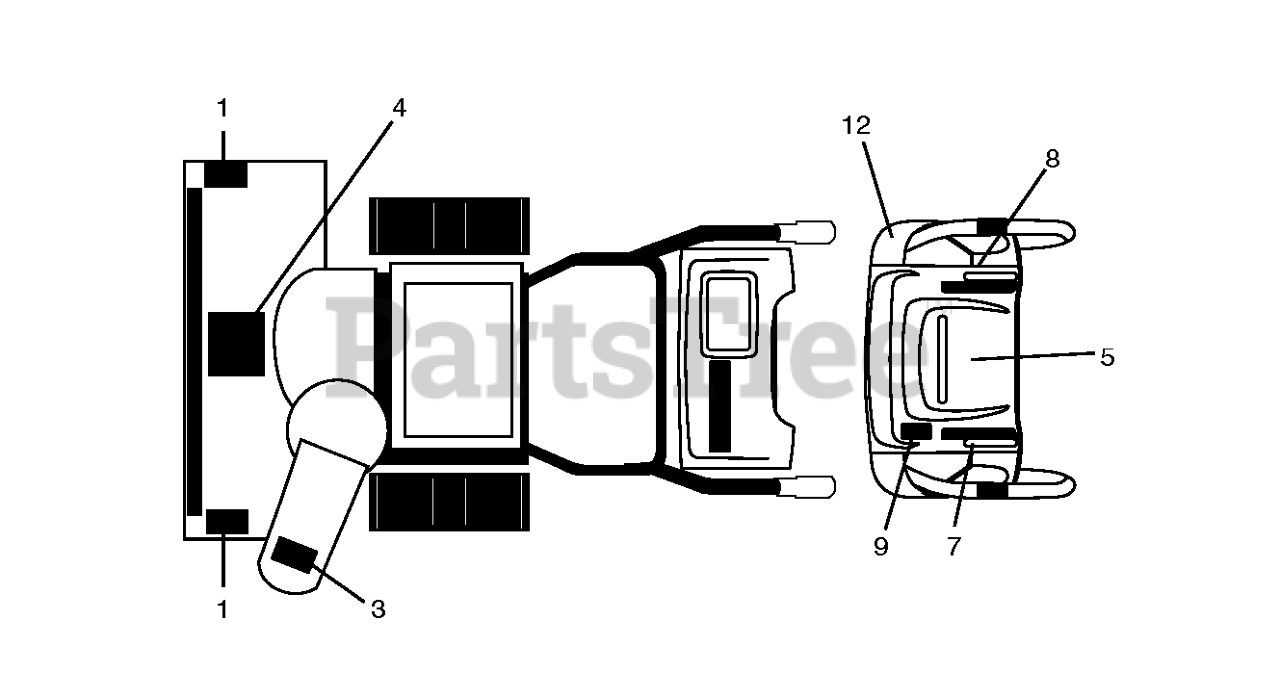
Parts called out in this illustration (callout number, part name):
1	DECAL.SNOWTHR.AUGER
3	DECAL.SNOWTHR.CHUTE.SAFETY
4	DECAL.SNOWTR.READ.OWN.MAN.E/F
5	DECAL.CONSOLE.SNOW.INST.ENG/FR
7	DECAL.CONS.LH.REM TANK.INST.GR
8	DECAL.CONS.RH.INST.GRY
9	DECAL,HEIGHTADJUST
12	DECAL.CONSOLE.HAND.WARMER
